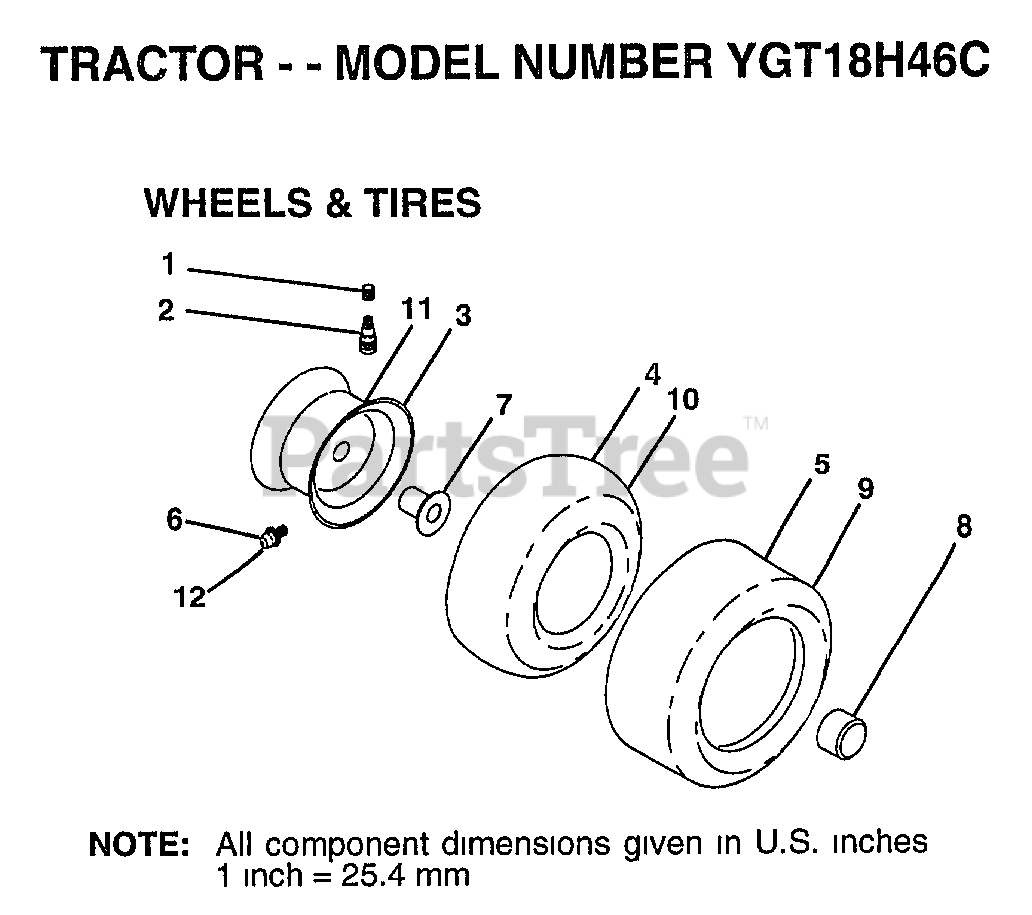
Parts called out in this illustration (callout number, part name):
1	VALVE CAP
2	VALVE STEM LT
3	"RIM ASM 8"" FRT"
4	TUBE.16X6.5/7.5-8
6	FITTING LT
7	"FLANGE, BEARING"
8	HUB CAP
10	TUBE.23X8/10-12
11	"RIM ASM 12"" REAR"
12	ZERK FITTING M
